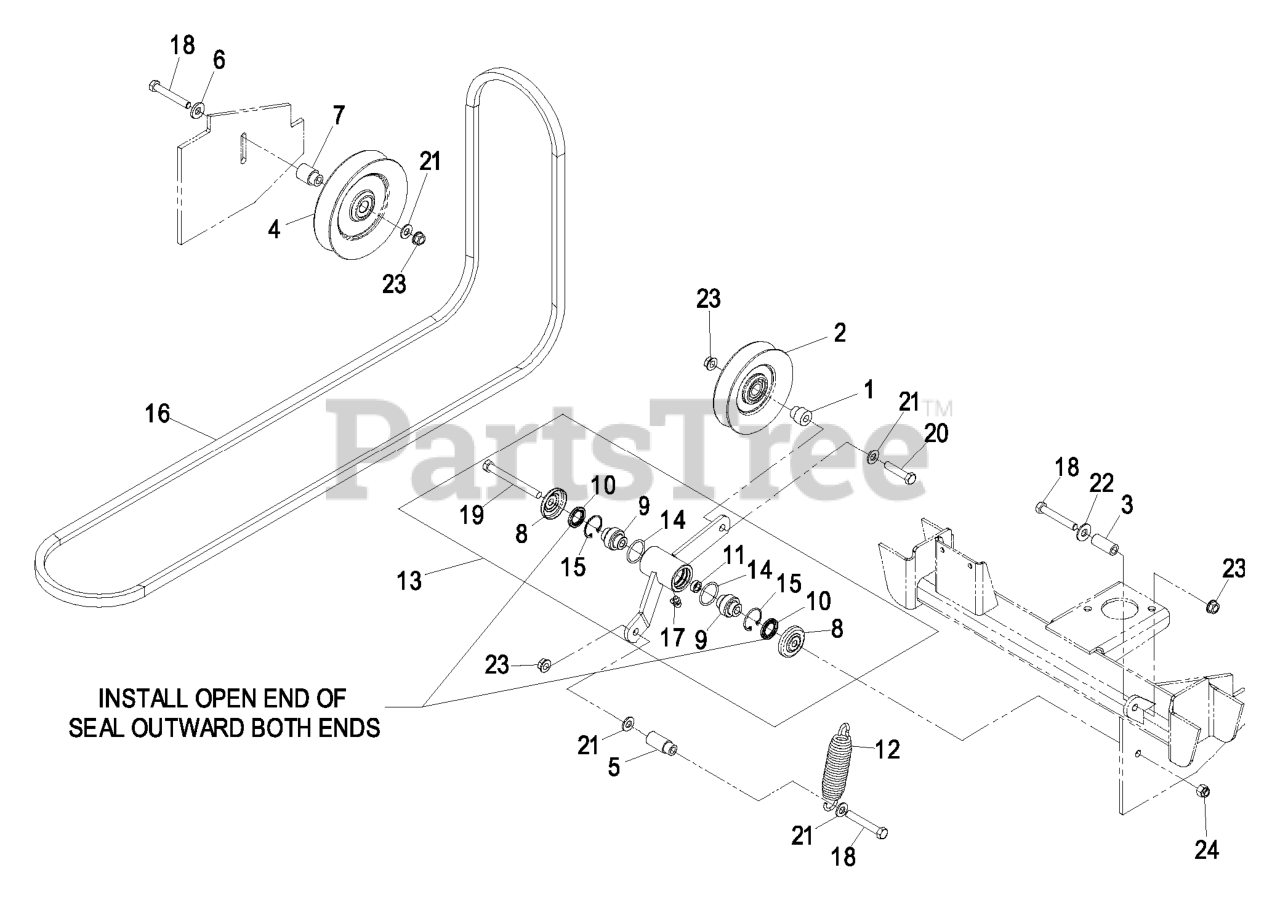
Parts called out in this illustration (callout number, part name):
1	BUSHING-IDLER
2	PULLEY-IDLER
3	BUSHING-LEVER, LIFT
4	PULLEY-IDLER
6	WASHER-BELLEVILLE
7	BUSHING-IDLER
8	GUARD-TOP
9	BEARING-SPHERICAL
10	SEAL-LIP, SINGLE
15	RING-SNAP
17	FITTING-GREASE, 90 DEG
18	BOLT-CARR
19	SCREW-HH
20	SCREW-HH
21	WASHER-FLAT
22	WASHER-FLAT
23	NUT-HHF, WHIZ
24	NUT-LOCK, NI
